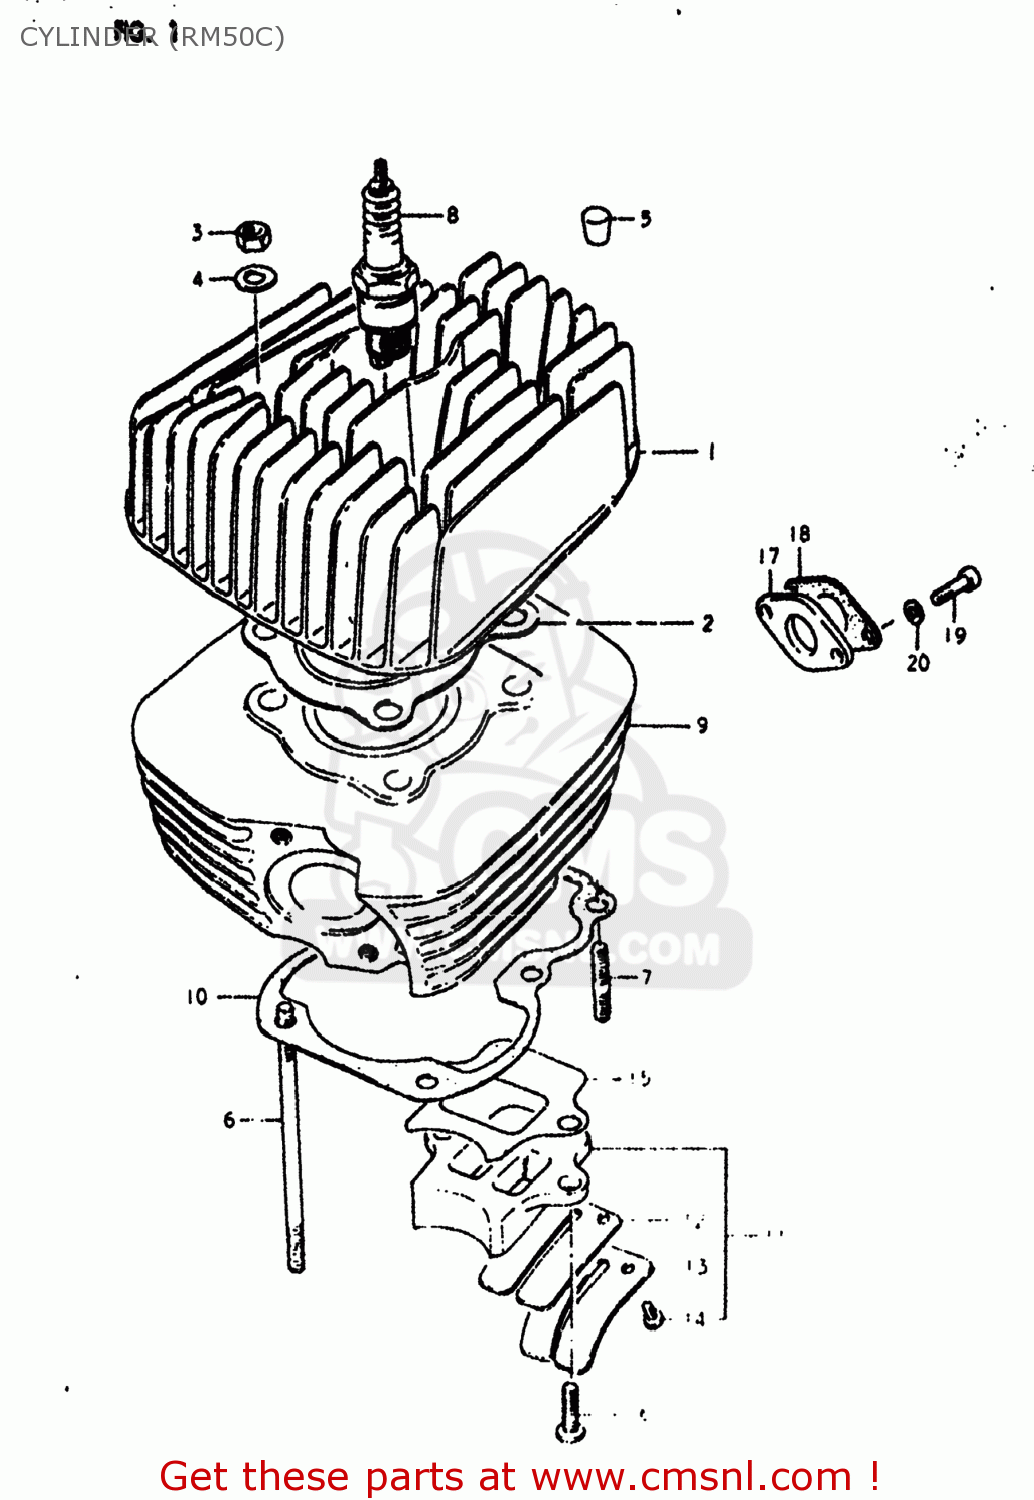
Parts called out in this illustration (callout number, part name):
1	HEAD,CYLINDER
2	GASKET,CYLINDER HEAD (NAS)
3	NUT
4	WASHER
5	PAD,CYLINDER HEAD
6	BOLT,STUD
7	STUD 6X16
8	SPARK PLUG
9	CYLINDER
10	GASKET,CYLINDER (MCA)
11	VALVE ASSEMBLY,REED
12	STOPPER,REED VALVE
13	VALVE,REED
14	SCREW,REED VALVE
15	GASKET,REED VALVE (MCA)
16	SCREW
17	INSULATOR,CARBURETOR
18	GASKET,CARBURETOR (MCA)
19	BOLT
20	WASHER
